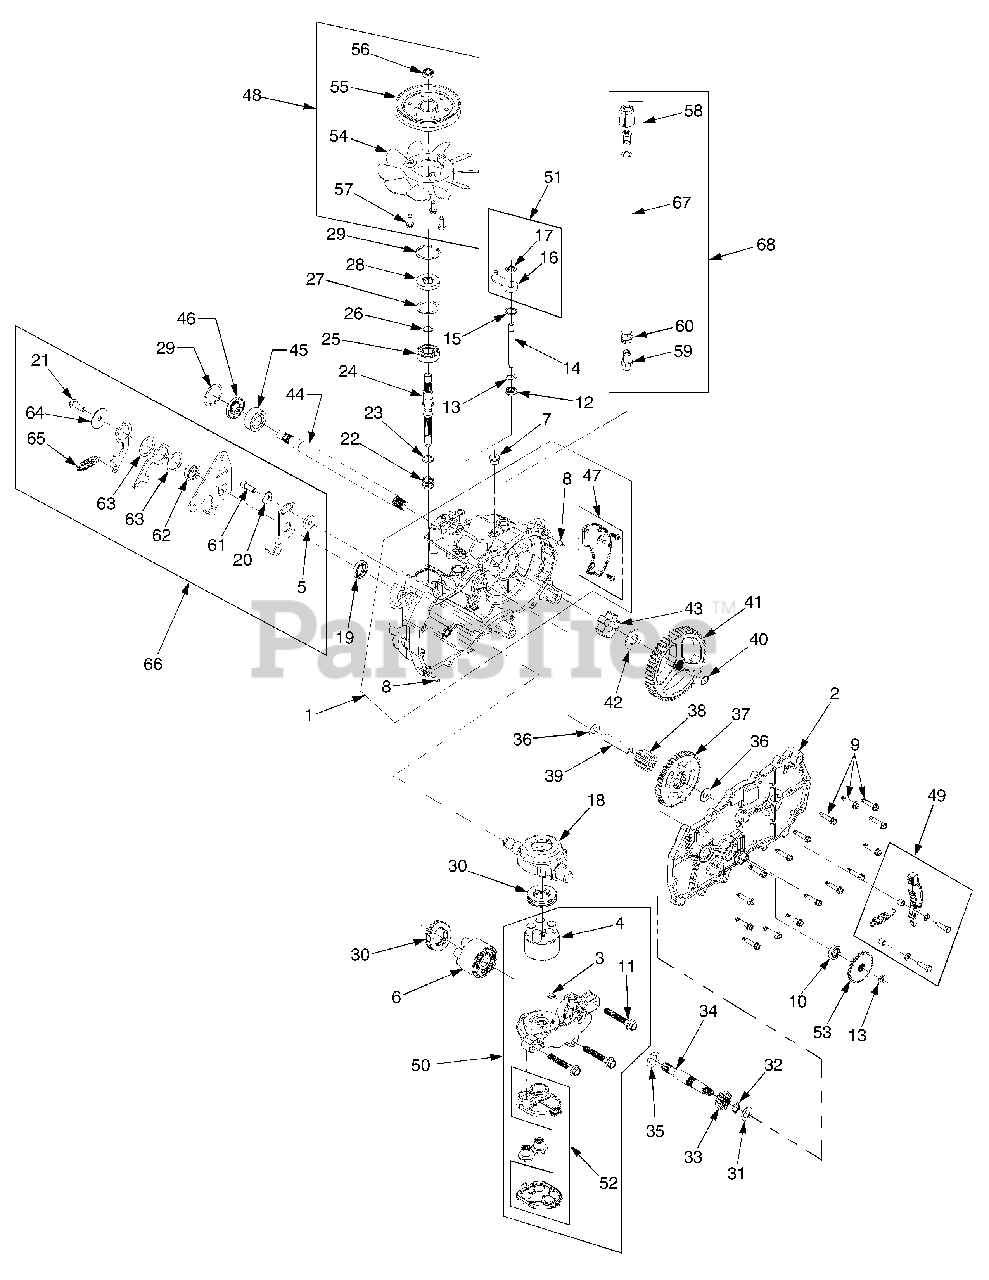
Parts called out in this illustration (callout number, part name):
1	Housing Assembly, Main RH
2	Side Assembly, RH
3	Plate, Bypass
4	Pump Block Assembly
5	Spacer, .32 x 1.005
6	Motor Block Assembly
8	Pin, Stainless
9	Screw, Hex Self Tapping, 1/4-20 x 1.25
10	Seal, Brake
11	Bolt, Hex Flange, 3/8-24 x 2.5
12	Seal, Lip, .375 x .75 x .25
13	Ring, Retaining, .375 Ext.
14	Rod, Bypass
15	Ring, Retaining, .75 Int.
16	Arm, Bypass
17	Ring, Retaining, .375 Push
18	Swashplate, Trunnion
19	Seal, Lip, 18 x 32 x 7
20	Washer, Flat, 11/32 x 7/8 x 1/16
21	Screw, 5/16-24 x 1.0
22	Spring, Compression
23	Washer, .591 x .787 x .04
24	Shaft, Input
25	Bearing, Ball, 17mm x 40 x 12
26	Ring, Wire Retaining, .561
28	Seal, Lip, 17 x 40 x 7
29	Ring, Retaining
30	Bearing, Thrust, 30 x 52 x 13
31	Washer, Flat, 5/8 x 1.0 x .05
32	Ring, Retaining
33	Gear, Pinion, 13T
34	Shaft, Motor
35	Washer, .71 x 1.16 x .04
36	Washer, HT, .5 x 1.0 x .032
37	Gear, 10T/48T
38	Gear, Jackshaft, 10T
39	Pin, Jackshaft
40	Ring, Spiral Retaining
41	Gear, Bull, 52T
42	Washer, 3/4 x 1.5 x .13
43	Bearing, Sleeve
44	Axle, spline
45	Bushing, .752 x 1.571 x .625
46	Seal, Lip, .75 x 1.577 x .25
47	Kit, Expansion Plate, RH
48	Kit, Fan-Pulley
49	Kit, Brake Arm
50	Kit, Center Section-Filter RH
51	Kit, Bypass Arm
52	Kit, Filter
53	Disc, Brake Cog
54	Fan, 7" 10 Blade
55	Pulley, 4.5
56	Nut, Hex Insert Lock, 1/2-20
57	Screw, Hex Wash. Hd. Tapp 1/4-20
58	Cap, Vent Assembly
59	Fitting, Sraight, 9/6-18
60	Clamp, Pinch
61	Screw, Hx Patch, 5/16-24 x 1.0
62	Bushing, Pilot, 1.125
63	Washer, Plastic
64	Washer, 1.5 x .34 x .062
65	Spring, Extension
66	Kit, Return Assembly
67	Hose, .5 x 15.0
68	Kit, Breather Assembly
